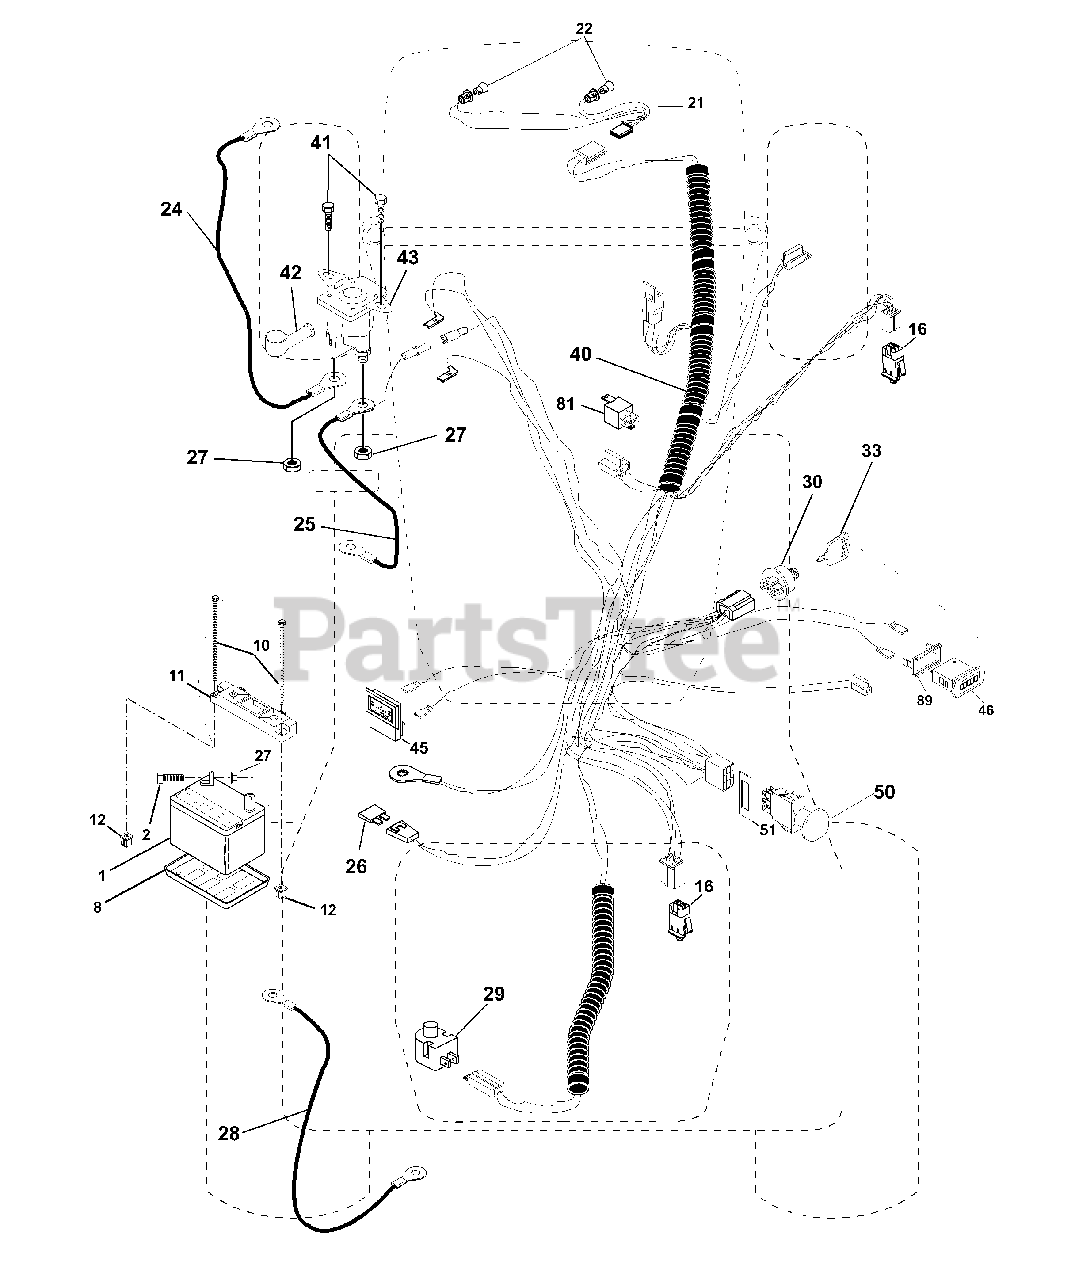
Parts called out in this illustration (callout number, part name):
1	Battery
2	Bolt Hex Head 1/4-20 x 3/4
8	Tray, Battery
10	Bolt Btr Frt 1/4-20 X 7.5 zinc
11	Holdown Battery Front Mount
12	Nut Push Nylon 1/4"
16	Switch Interlock Push-In
21	Harness Socket Light
22	Bulb Light
24	Cable, Battery
25	Cable, Battery
26	Fuse
27	Nut Keps Hex 1/4-20
28	Cable,Ground
29	Switch, Plunger
30	Switch, Ign
33	Key
40	Harness, Ignition
41	Screw 1/4-20 x 1/2
42	Cover, Terminal Red
43	Solenoid
45	Ammeter
46	Meter Hour
50	Switch, PTO
51	Ring Retainer PTO
81	Relay Asm.
89	Bracket Snap-IN Hourmeter
